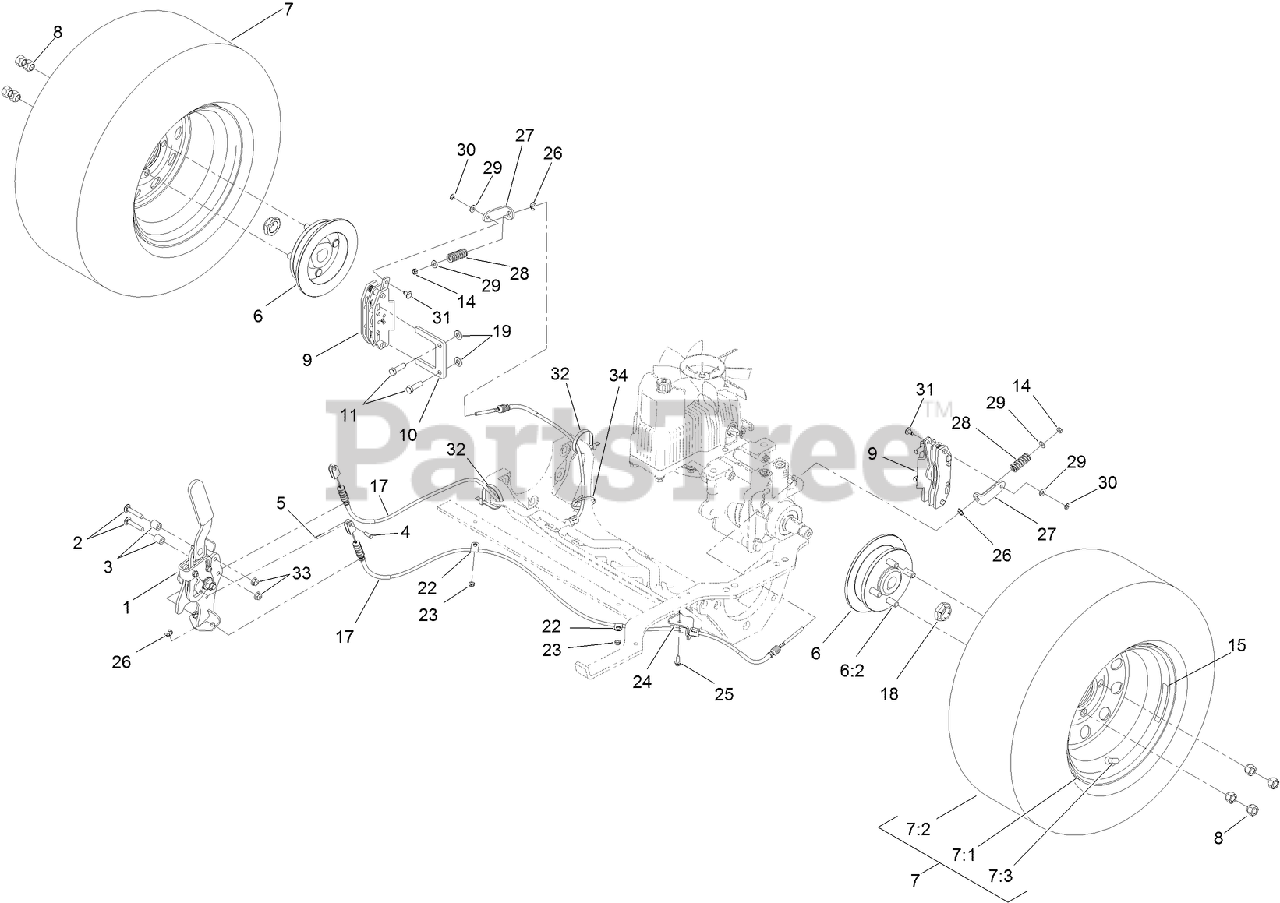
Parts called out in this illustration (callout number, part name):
1	BRAKE HANDLE ASM
2	SCREW-CARR
3	SPACER
4	PIN-CLEVIS
5	PIN-COTTER
6	WHEEL HUB ASM
6:2	STUD-WHEEL
7	WHEEL AND TIRE ASM
7:3	STEM-VALVE
8	NUT-LUG
9	CALIPER-BRAKE
10	PLATE-MOUNT, BRAKE
11	SCREW-LOCK, PATCH
14	NUT-LOCK, NI
15	DECAL-TORQUE, WHEEL HUB LUG
17	CABLE-BRAKE
18	LOCKNUT
19	WASHER-FLAT
23	NUT-LOCK, NI
24	BRACKET-CABLE
25	SCREW-HWH
26	E-RING
27	BRACKET-BRAKE, L
28	SPRING-DIE
29	WASHER-FLAT
30	E-RING
31	PIN-BRAKE
32	TIE-CABLE
33	NUT-HF, NI
34	TIE-CABLE
